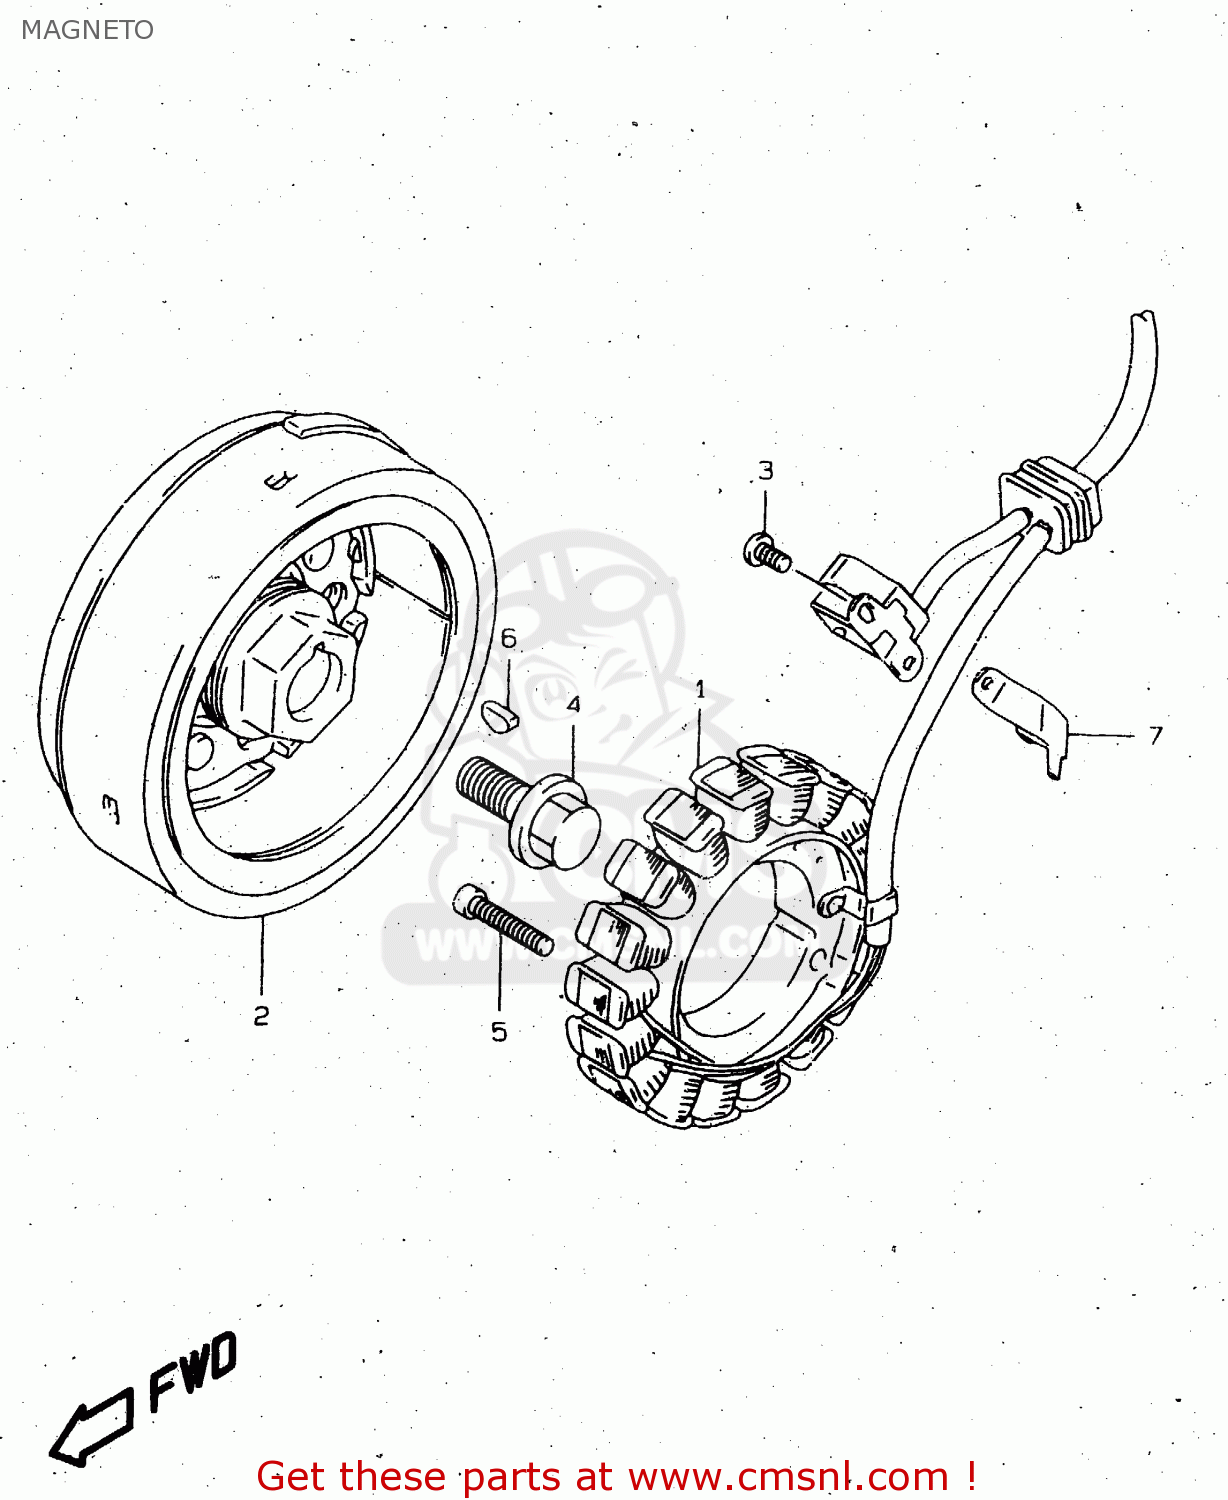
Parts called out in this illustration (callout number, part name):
1	STARTER ASSY
2	ROTOR ASSY
3	SCREW
4	BOLT(14X43)
5	BOLT
6	KEY
7	CLAMP,MAGNETO LEAD
